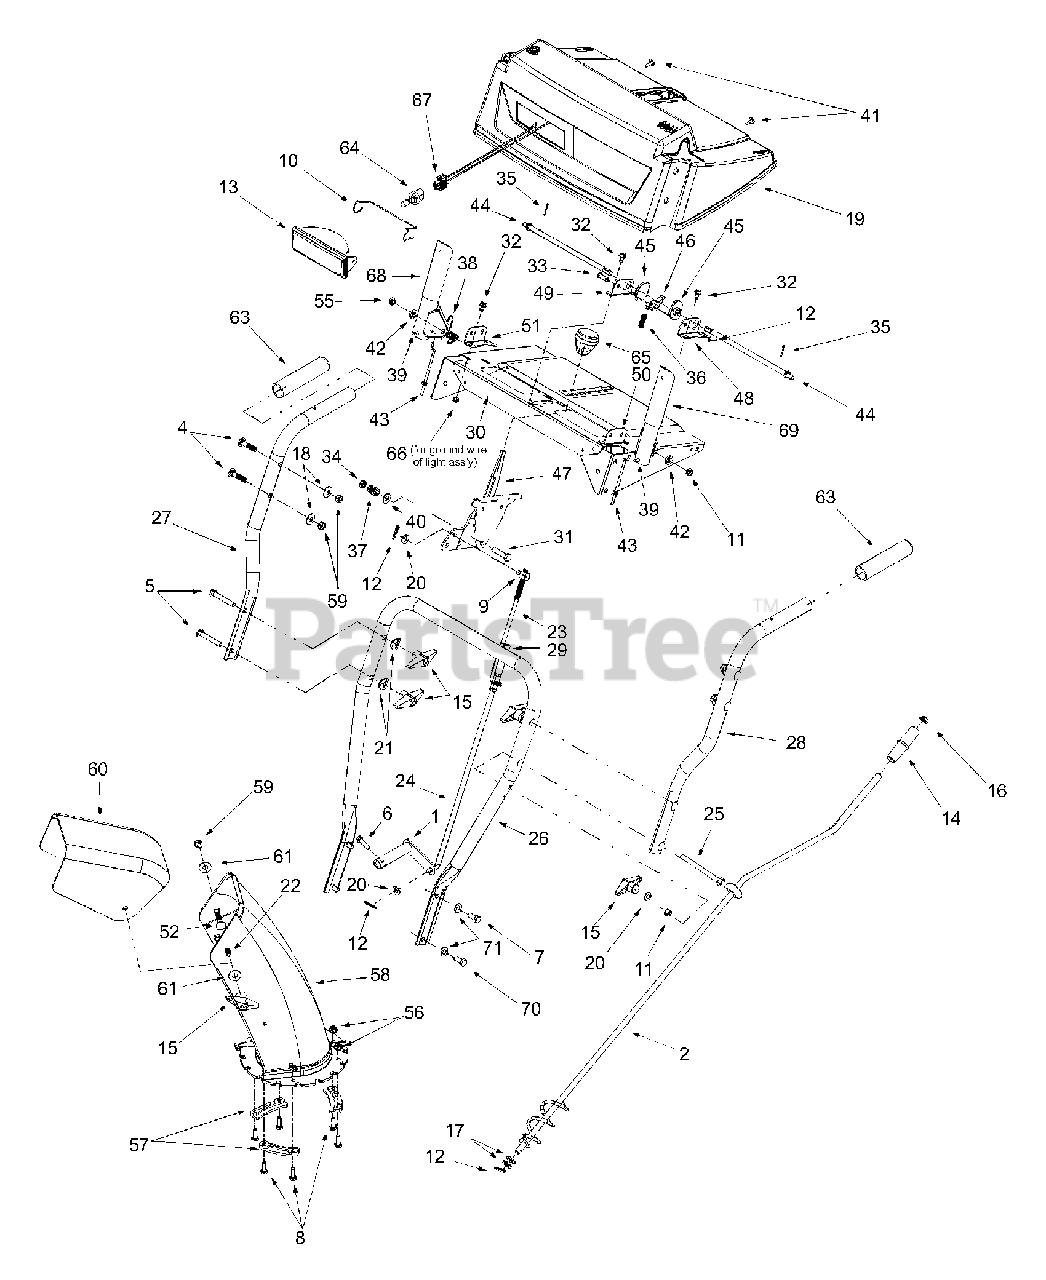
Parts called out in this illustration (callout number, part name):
2	Chute Crank Ass'y
4	Carriage Bolt, 5/16-18 x 1.75
5	Carriage Bolt, 5/16-18 x 2.25
6	Self Tapping Screw, 1/4-20 x 1
7	Hex Cap Screw, 5/16-18 x 1.0
8	Hex Cap Screw, 1/4-20 x .75
9	Ferrule, 5/16-18 x .312
10	Headlamp Retainer
11	Hex Nut, 5/16-18
12	Internal Cotter Pin
13	Lens Assembly / Lamp Housing
14	Chute Crank Knob
15	Wing Knob, 5/16-18
16	Push Cap, 3/8
17	Flat Washer, .375 x .738 x .063
18	Bell Washer, .34 x .872
19	Plastic Handle Panel (Black)
20	Flat Washer, .344 x .688 x .065
21	Saddle Washer, .32 x .93
22	Carriage Screw, 5/16-18 x 1
23	Upper Shift Rod
24	Lower Shift Rod
25	Eyebolt
32	Self Tapping Screw, 1/4-20 x .5
33	Clevis Pin
34	Jam Nut, 3/8-24
35	Internal Cotter Pin
36	Compression Spring, .36 x 1.0
37	Comp. Spring, .39 x .6 x .88
38	Torsion Spring, .44 x .8
39	Rubber Bumper
40	Bell Washer, .401 x .87 x .063
41	Special Screw, #10-16 x .625
42	Special Washer, .35 x .72 x .13
43	"Z" Fittings For Control Cables
44	Cam Rod
45	Cam Handle Lock
46	Handle Lock Pawl
52	Carriage Bolt, 5/16-18 x .75
55	Hex Lock Nut, 5/16-18
56	Hex Flange Lock Nut, 1/4-20
57	Lower Chute Flange Keeper
58	Lower Chute
59	Hex Lock Nut, 5/16-18
60	Upper Chute
61	Washer, 5/16
63	Handle Grip
64	Halogen Lamp, 12-volt, 27 Watt
65	Plastic Knob
66	Hex Sems Nut, 1/4-20
67	Halogen Light Harness
68	RH Engagement Handle Ass'y
69	LH Engagement Handle Ass'y
70	Hex Cap Screw, 5/16-18 x .75
71	Lock Washer, 5/16
